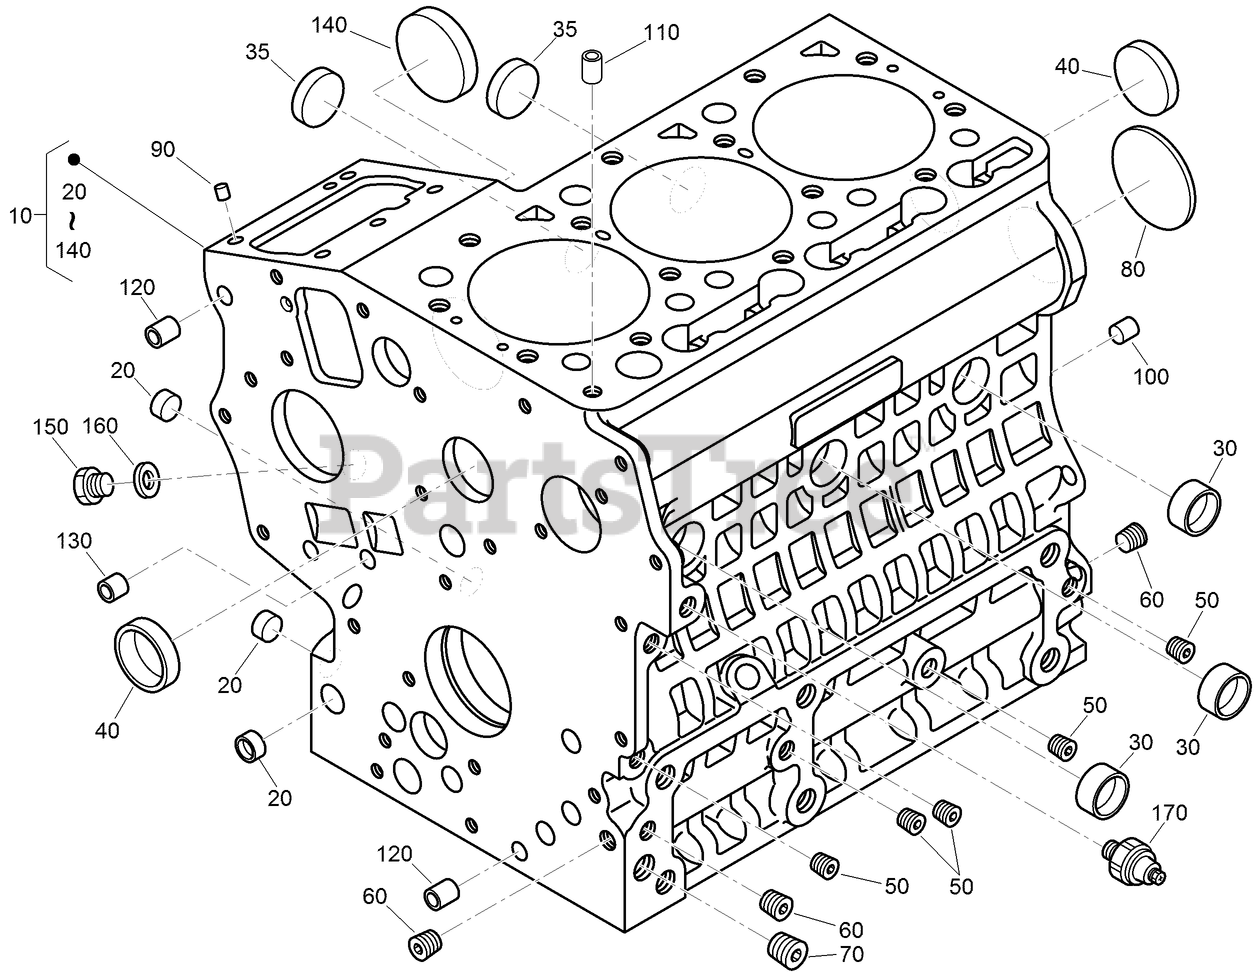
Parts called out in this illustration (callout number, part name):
10	CRANKCASE ASM
20	CAP-SEALING
30	CAP-SEALING
35	CAP-SEALING
40	CAP-SEALING
80	PLUG-EXPANSION
90	PIN-STRAIGHT
100	PIN-STRAIGHT
110	PIN-PIPE
120	PIN-PIPE
130	PIN-PIPE
140	COVER-FUEL, CAMSHAFT
160	WASHER
170	SWITCH-OIL
